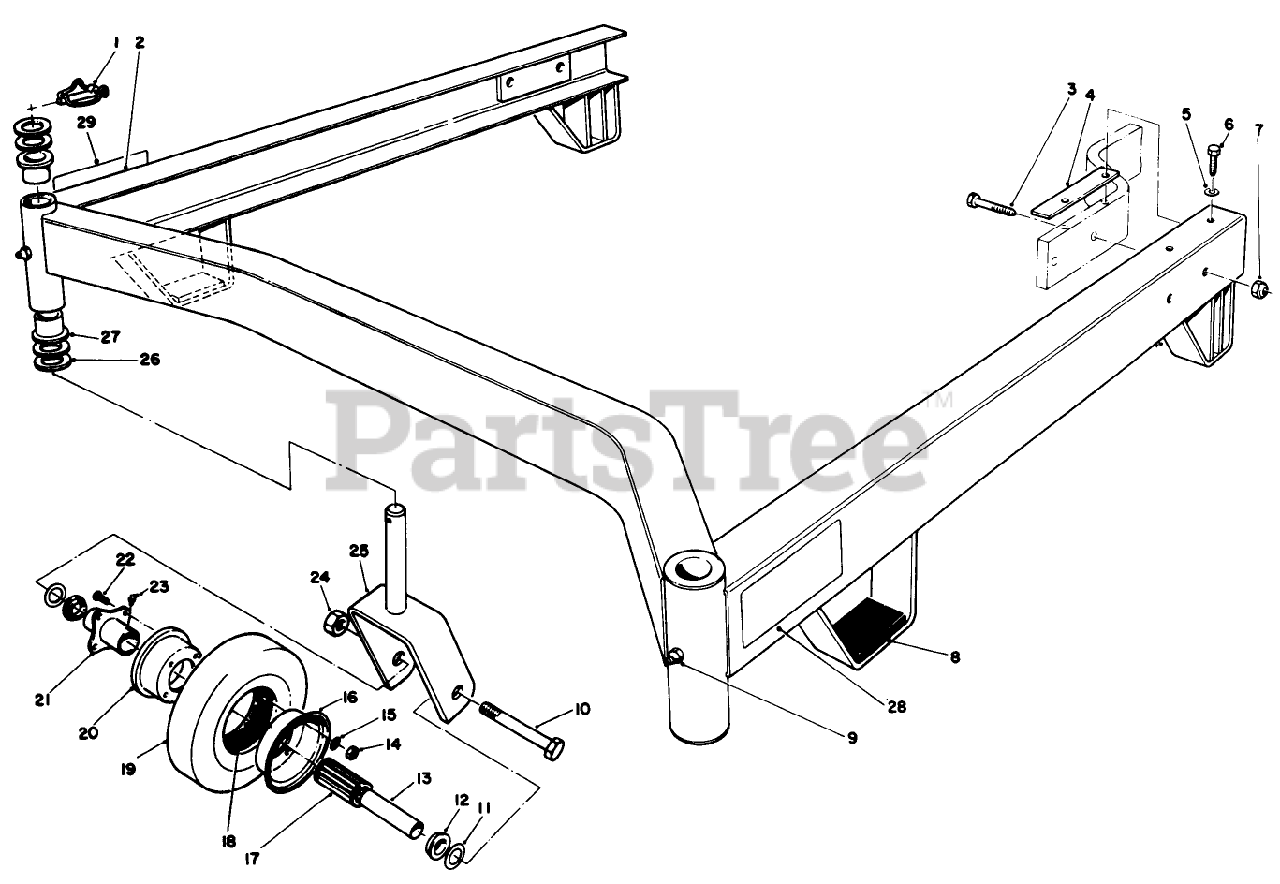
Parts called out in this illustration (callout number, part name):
1	PIN-LYNCH
2	Suspension Assembly (Incl. Ref. #9 & 27)
3	SCREW-HH
4	SHIM-CARRIER
5	WASHER-FLAT
6	SCREW W/PATCH
7	NUT-LOCK, CONE
8	Pad-Rubber
9	FITTING-GREASE
10	SCREW-HH
11	WASHER-FLAT
12	BEARING-OUTSIDE
13	SPANNER-TIRE
14	NUT-HEX
15	WASHER-LOCK
16	MALE WHEEL HALF
17	BEARING-ROLLER
18	TUBE-INNER (W/VALVE)
20	FEMALE WHEEL HALF
21	HUB-CENTER
22	WHEEL BOLT
23	FITTING-GREASE
24	NUT-HEX
25	Castor Fork
26	WASHER-THRUST
27	Bushing
28	DECAL-HOC, RH
29	DECAL-HOC, LH
